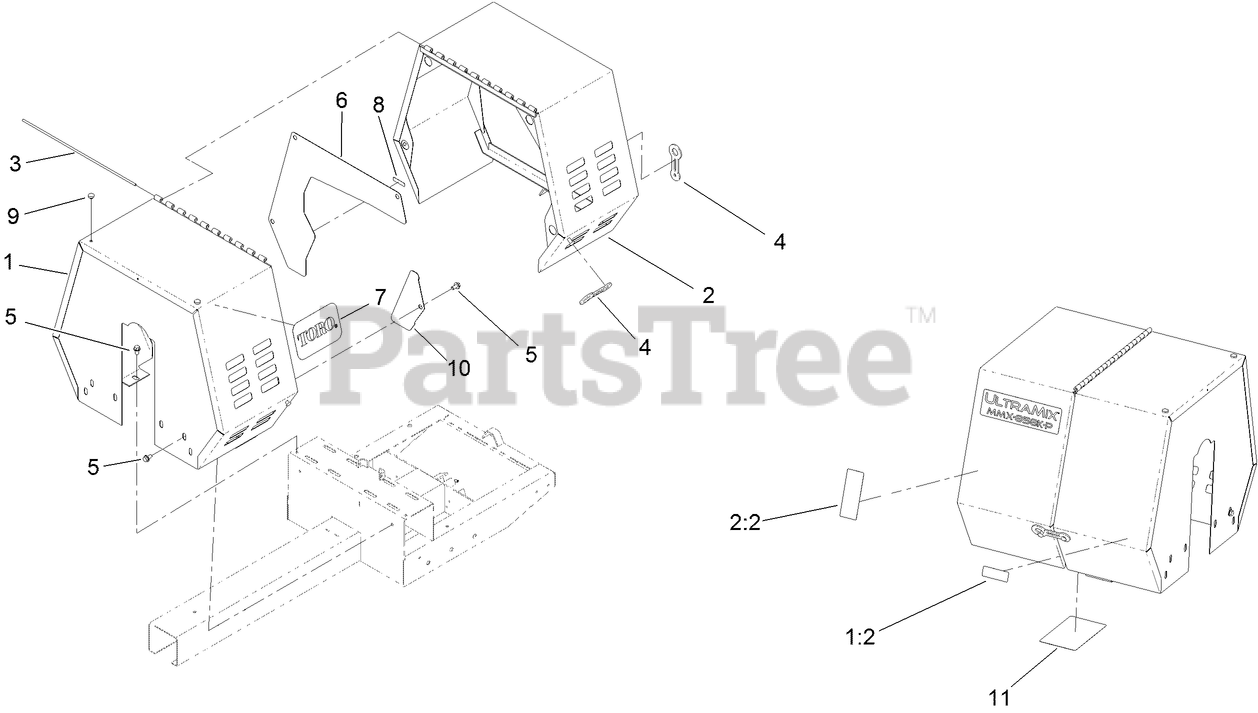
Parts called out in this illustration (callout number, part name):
1	STATIONARY COWL ASM
1:2	DECAL-ARRESTER, SPARK
2	MOVABLE COWL ASM
2:2	DECAL-WARNING
4	LATCH-RUBBER
5	SCREW-HWH
6	PLATE-ACCESS, BELT
7	DECAL
8	DECAL-GREASE
9	BUMPER
10	PLATE-ACCESS, BELT
11	DECAL-SERVICE
